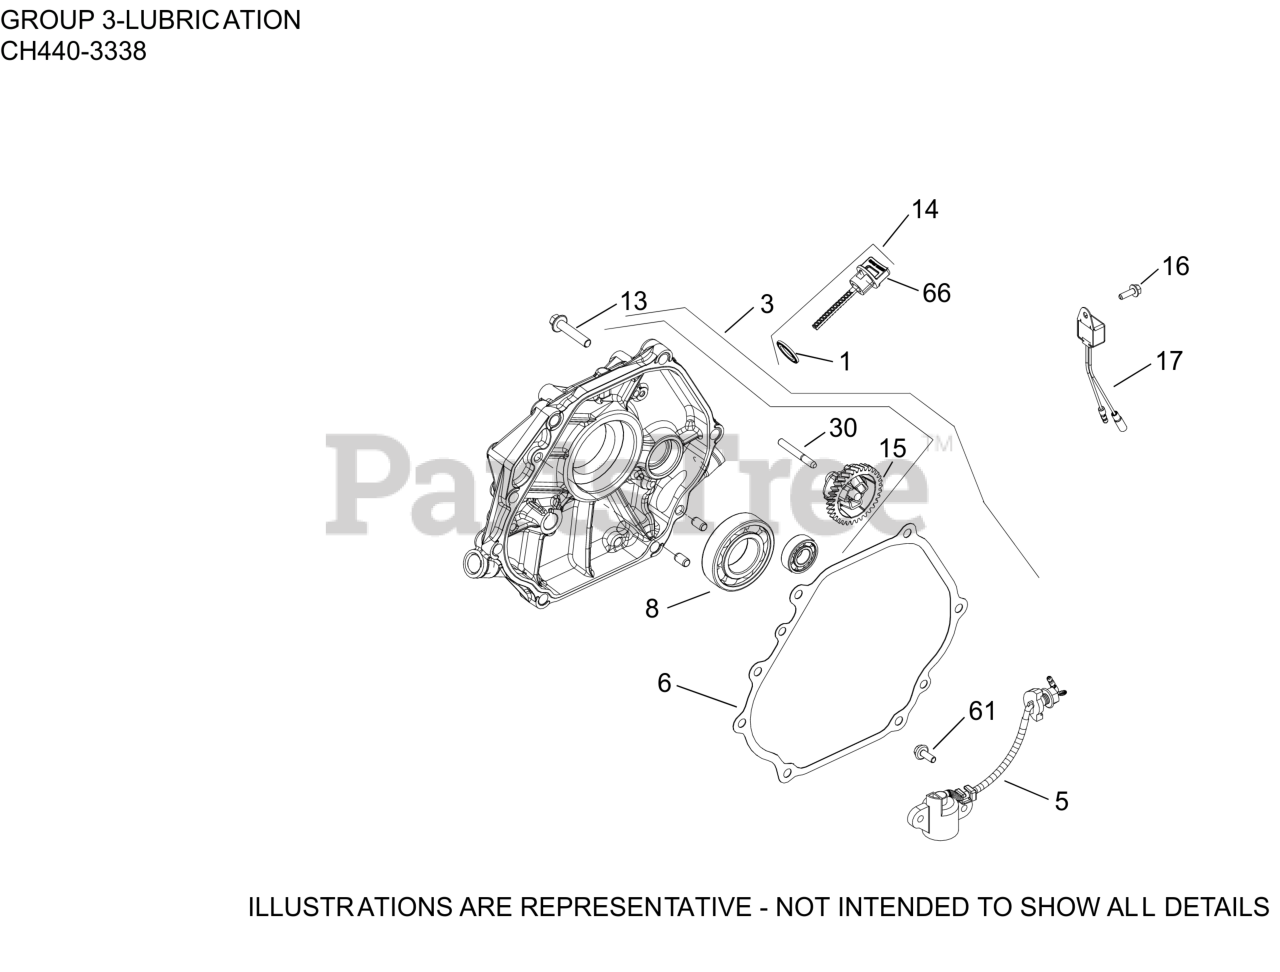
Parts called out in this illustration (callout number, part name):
1	SEAL, DIPSTICK
3	KIT, CLOSURE PLATE ASSEMBLY
5	SWITCH, OIL SENSOR ASSEMBLY
6	GASKET, CLOSURE PLATE
8	BEARING, BALL
13	SCREW, CLOSURE PLATE
14	DIPSTICK ASSEMBLY
15	GOVERNOR ASSEMBLY
16	SCREW, HEX/PHILLIPS M5
17	OIL ALERT CONTROL UNIT
30	SHAFT, GOVERNOR GEAR
61	SCREW, M6 X 16
66	DIPSTICK - USE 17 038 08-S
